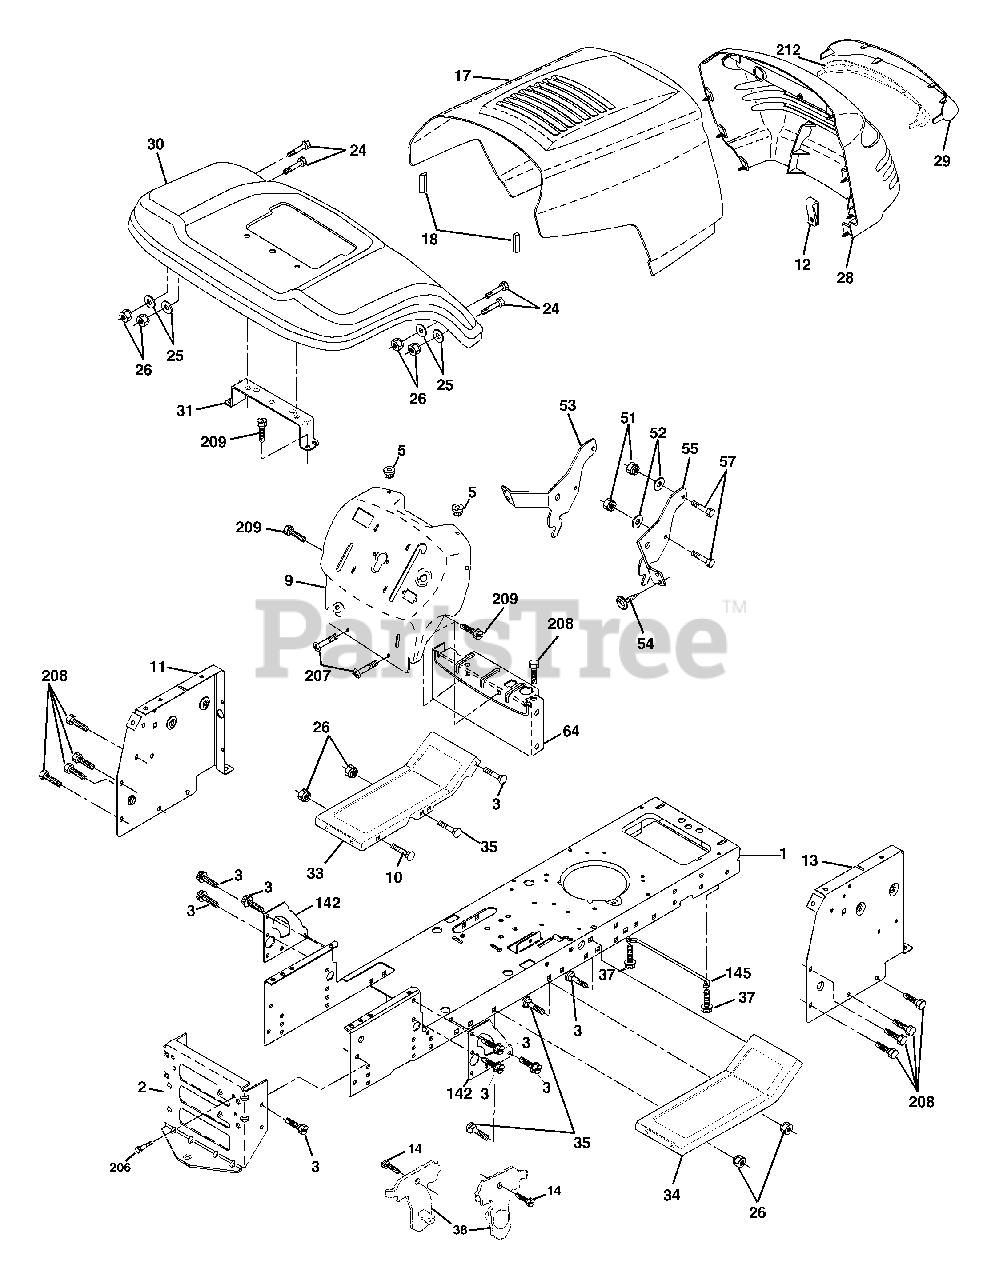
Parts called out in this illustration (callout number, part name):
1	Chassis
2	Drawbar
3	Screw 3/8-16 x 3/4
5	Bumper Hood/Dash
10	Bolt Rd Hd Sqnk. 3/8-16 Unc x 1
11	Panel Asm. Dash Lh
12	Clip Tinnerman Grile P/L
13	Panel Dash Rh
17	Hood
18	Bumper Hood
24	Bolt Fin Hex 3/8-16 Unc x 1 Gr. 5
25	Washer 13/32 x 13/16 x 12 Ga.
26	Nut Lock Hex w/Insert 3/8-16 UNC
28	Grill/Lens Asm
29	Lens Grille
30	Fender Asm
31	Bracket Fender
33	Footrest LH
34	Footrest RH
35	Bolt Rd Hd Sht. Sqnk. 3/8-16 x 3/4
37	Screw Thdrol 5/16-18 x 1/2 Tyt
38	Bracket Asm. Pivot Mower Rear
51	Nut Lock Hex W/Ins. 1/4-20
52	Washer 9/32 x 7/8 x 16 Ga.
53	Bracket Grille LH
54	Screw Hex Wshd 8-18 x 7/8
55	Bracket, Grille RH
57	Bolt Fin Hex 1/4-20 x .75
64	Dash Lower
142	Plate Reinforcement
145	Rod Pivot Chassis/Hood
205	Screw Thdrol 3/8-16 x 1/2
206	Bolt shoulder 5/16-18
207	Screw Thdrol 5/16-18 x 1/2
208	Screw Thdrol 3/8-16 x 1/2
209	Screw 3/8-16 x 3/4
212	Insert Lens Reflector
